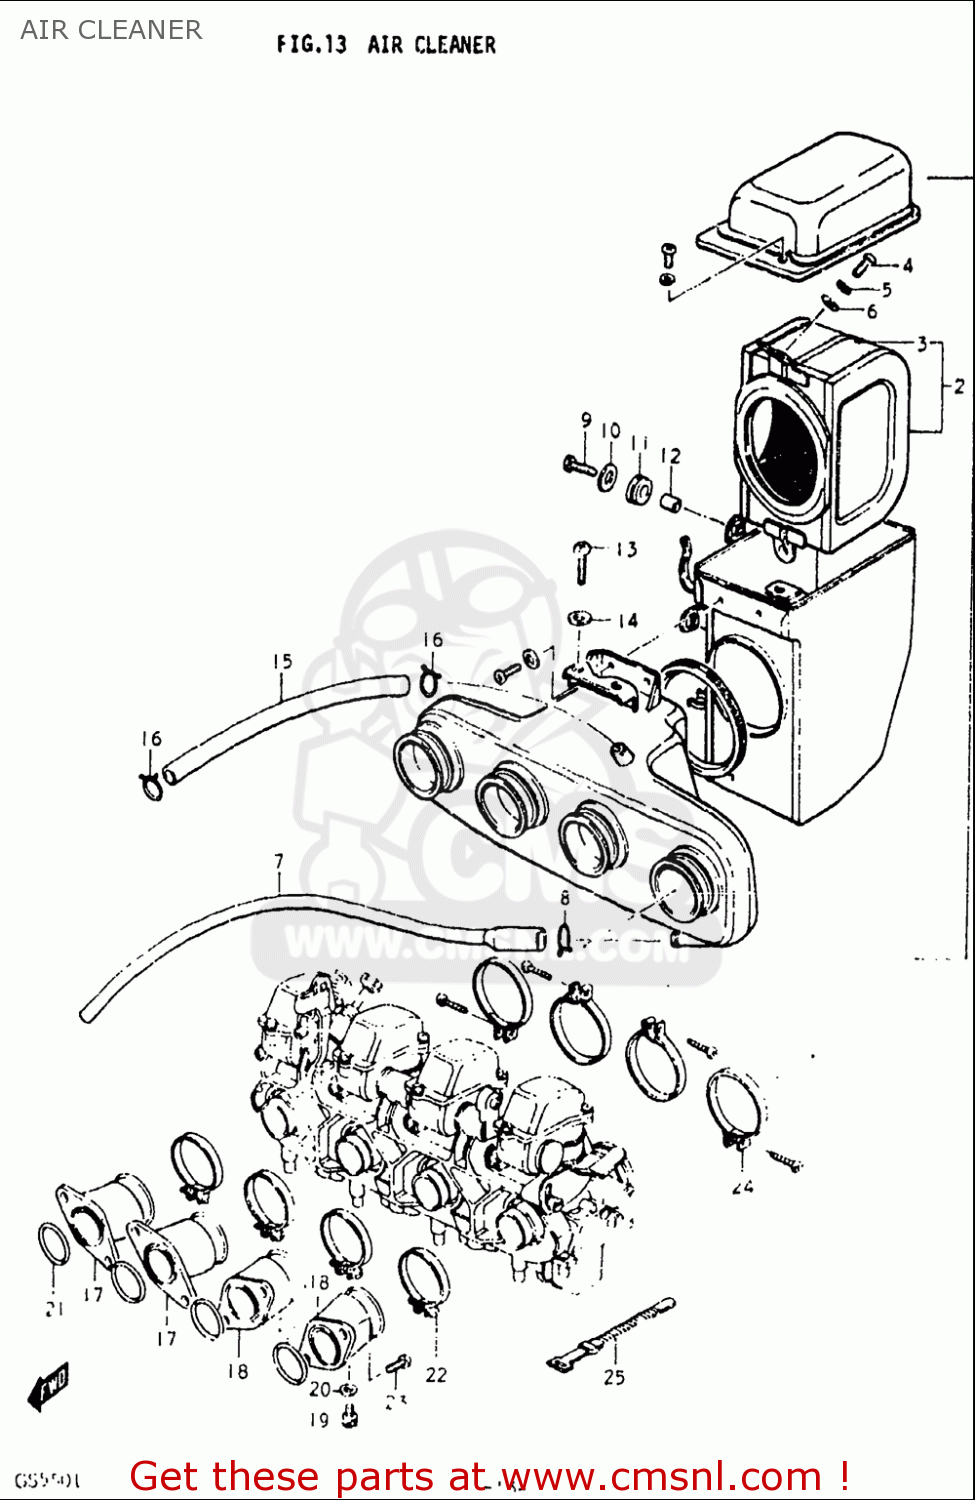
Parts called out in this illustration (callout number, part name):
2	FILTER ASSY
3	FILTER
4	SCREW
5	WASHER,LOCK
6	WASHER
8	CLIP
9	BOLT
10	WASHER(6.5X18X1.6)
11	CUSHION
12	SPACER(6.5X9X9)
13	SCREW
14	WASHER
15	HOSE(11X15X2000)
16	CLIP
17	PIPE,INTAKE,R
18	PIPE,INTAKE,L
19	BOLT
20	WASHER
21	O RING(D:2.4,ID:28.7)
22	CLAMP
23	SCREW
24	CLAMP
25	CLAMP(L:120)
